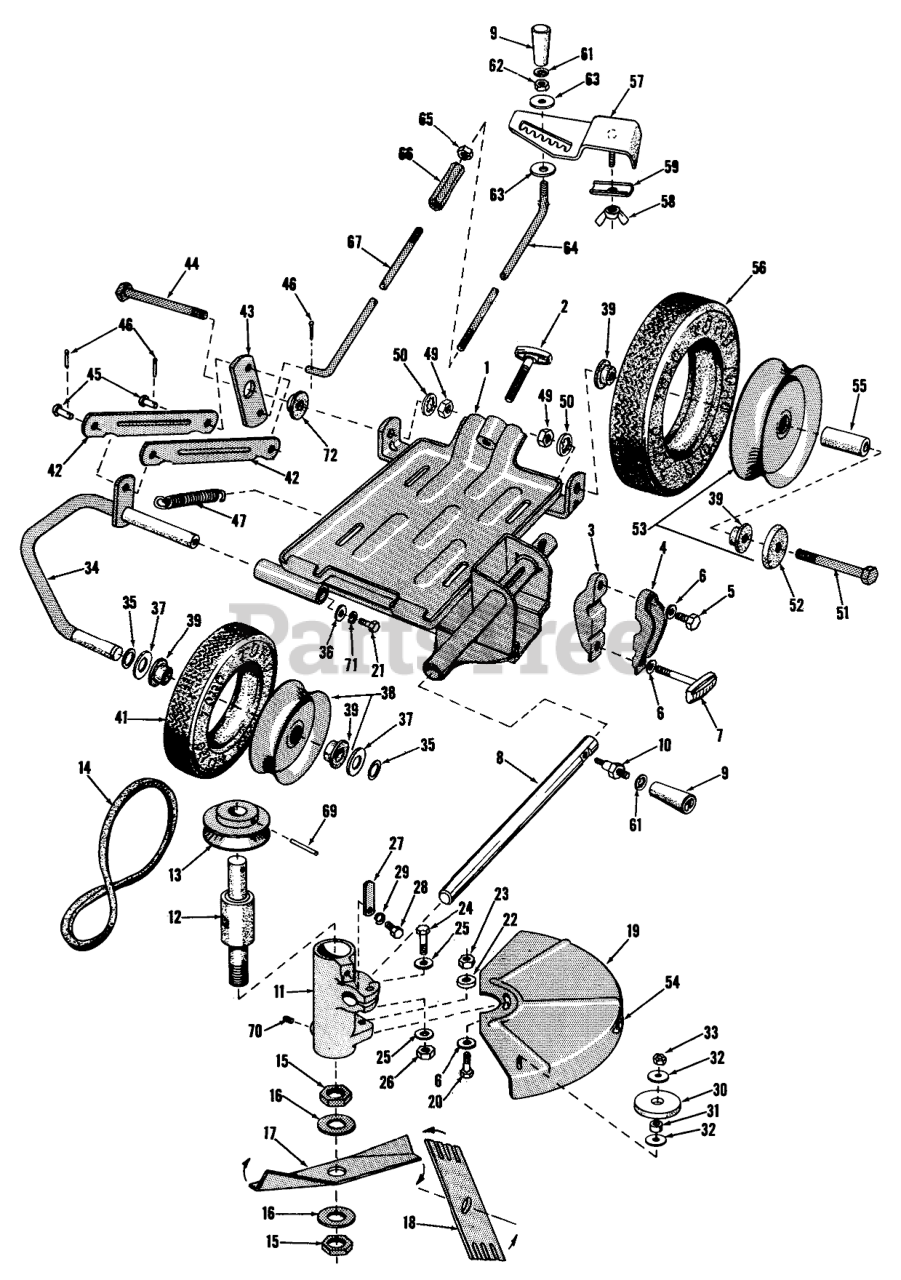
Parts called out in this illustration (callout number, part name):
1	Main Frame
2	Clamp Assy.
3	Beam Clamp Assy.
4	Beam Clamp
5	SCREW-HH
6	WASHER-PLAIN
7	Stud & Handle Assy.
9	Control Knob
10	Screw, Stop
11	Spindle Housing
12	Shaft & Bearing Assy.
13	Pulley
15	NUT-JAM
16	WASHER-FLAT
17	Blade, Trimming
18	EDGER BLADE B
19	Guard
20	SCREW-HH
21	SCREW-HH
22	WASHER-FLAT
23	NUT-LOCK
24	SCREW-HH
25	WASHER-FLAT
26	NUT-LOCK
27	Belt Guide
28	SCREW-HH
29	WASHER-LOCK
30	Trimming Roller
31	SPACER
32	WASHER-FLAT
33	NUT-LOCK, NI
34	Axle Assy.
35	Snap Ring
36	WASHER-FLAT
37	Washer
38	Wheel w/Bushings, Ref. 39
39	Bushing
41	Tires, 6"
42	Link, Connecting
43	Arm, Rear Axle w/Bushing Ref. No. 72
44	SCREW-HH
46	PIN-COTTER
47	Spring
49	NUT-JAM
50	WASHER-LOCK/INT
51	SCREW-HH
52	Hub Cap
53	Wheel w/Bushings, Ref. 39
54	Decal
55	Spindle, Left
56	8 TIRE
57	Control Panel
58	NUT-WING
59	Strap
61	WASHER-LOCK, INTERNAL
62	NUT-JAM
63	WASHER
64	Control Rod, Upper
65	NUT-JAM
66	Coupling
67	Control Rod, Lower
69	PIN-ROLL
70	SCREW-HSH
71	WASHER-LOCK
72	Bushing
